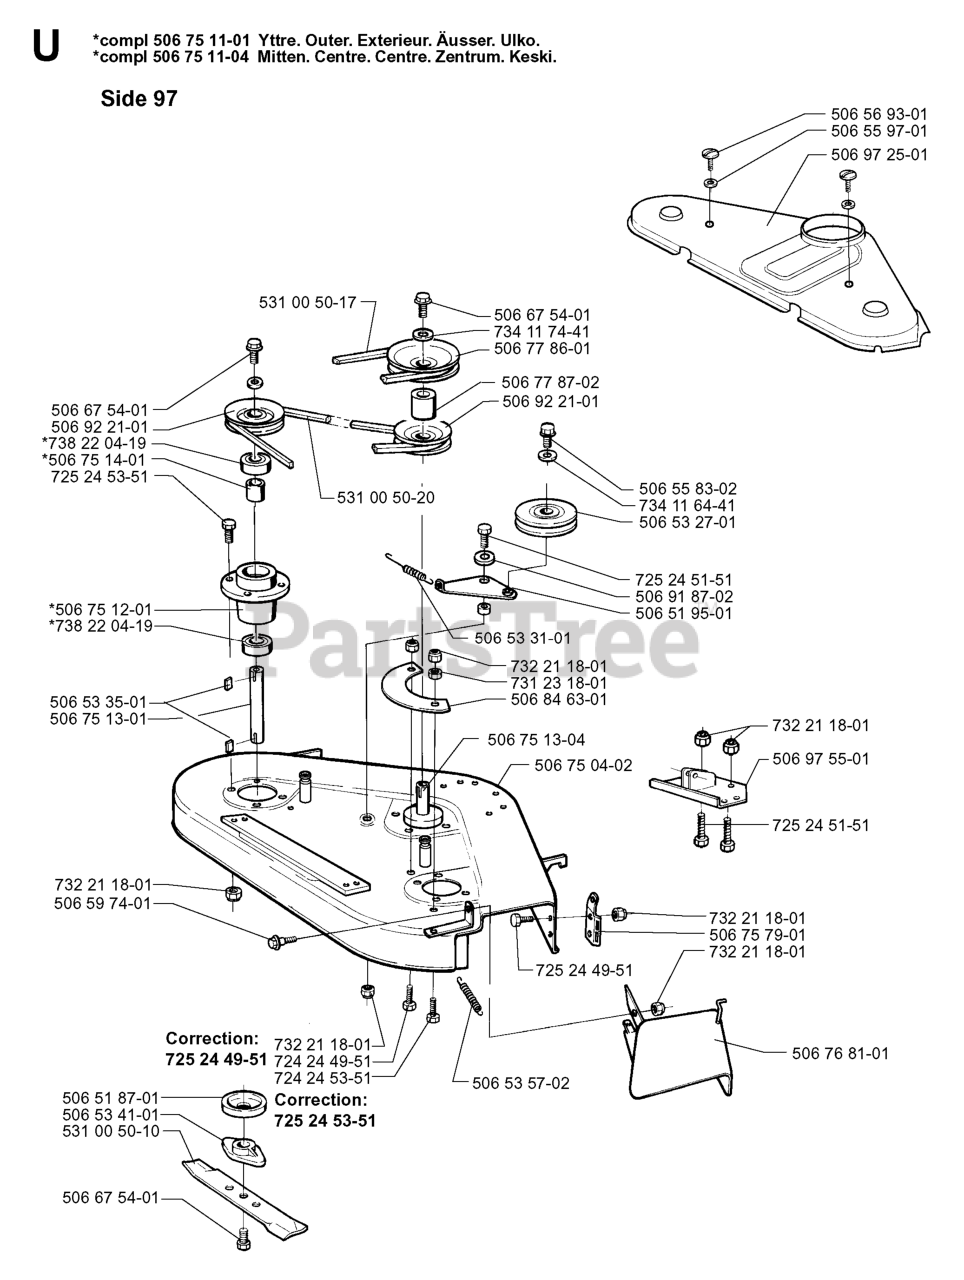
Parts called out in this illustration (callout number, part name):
2	SHAFT.ASM.CROSS.LIFT
3	LEVER.LIFT.HANDLE.GT
7	GRIP.HANDLE.LIFT.PVC.BLACK
10	SPRING.TORSION.LIFT.HANDLE
87	PIN.COTTER.7/16.BOW TI.
88	SPRING.LIFT.ASSIST.GT2
89	WASHER.CLEAR.ZINC
90	PIN.COTTER.5/16.BOW TI
91	LINK.ASM.LIFT.54"TG
97	SCREW, 3/8-16X3/4
98	LINK.ASM.SUSP.FRONT.MWR.10.5
